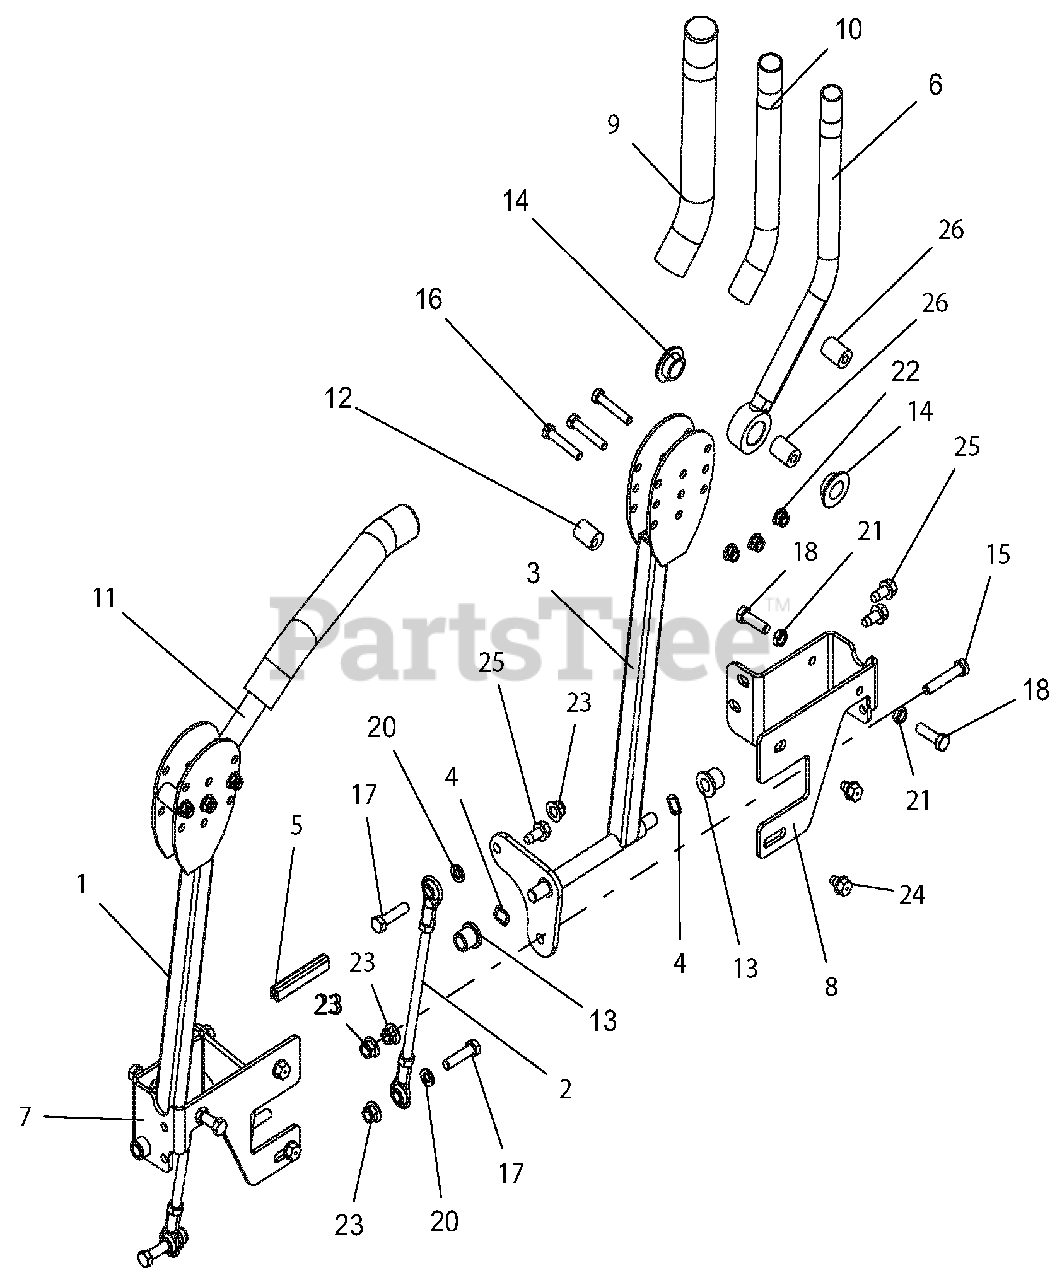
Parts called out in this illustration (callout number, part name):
1	WLDMT, PT/PT100 CONTROL ARM-BLACK
2	ASM, STEERING LINKAGE
3	WLDMT, LH PT/PT100 CONTROL ARM
4	WAVE WASHER .531X.781X.125 FH
5	STRIP, COWL - 1.50 LG
6	WLDMT, LH HANDLE
7	BRKT, RH STEERING STOP-RED
8	BRKT, LH STEERING STOP-RED
9	GRIP, HANDLEBAR
10	TUBE, .88ID X 1.00OD X 10.25
11	WLDMT, RH HANDLE
12	BSHG, ECCENTRIC .328 X .750 X .970
13	BHSG-FLG .500X.750X.750X.125
14	BSHG, FLANGE .762 X 1.48 X .44 NYLON
15	BLT-HEX .38-16X2.00 FTH GR5 YWZC
16	BLT-HEX .31-18X1.75 GR5 YWZC
17	BLT-HEX .38-16X1.50 GR5 YWZC
18	BLT-HEX .38-16X1.25 GR5 YWZC
20	WSHR-LK .38X.094 REG YWZC
21	NUT, JAM .375-16 YWZC
22	NUT-LK-NYL-FLG .31-18 YWZC
23	NUT-LK-NYL-FLG .38-16 YWZC
24	SCR-TAP .38-16X.50 HWH TR YWZ
25	SCR-TAP .38-16X.75 HWH TR YWZ
26	SPACER, .328 X .76 X 1.01
